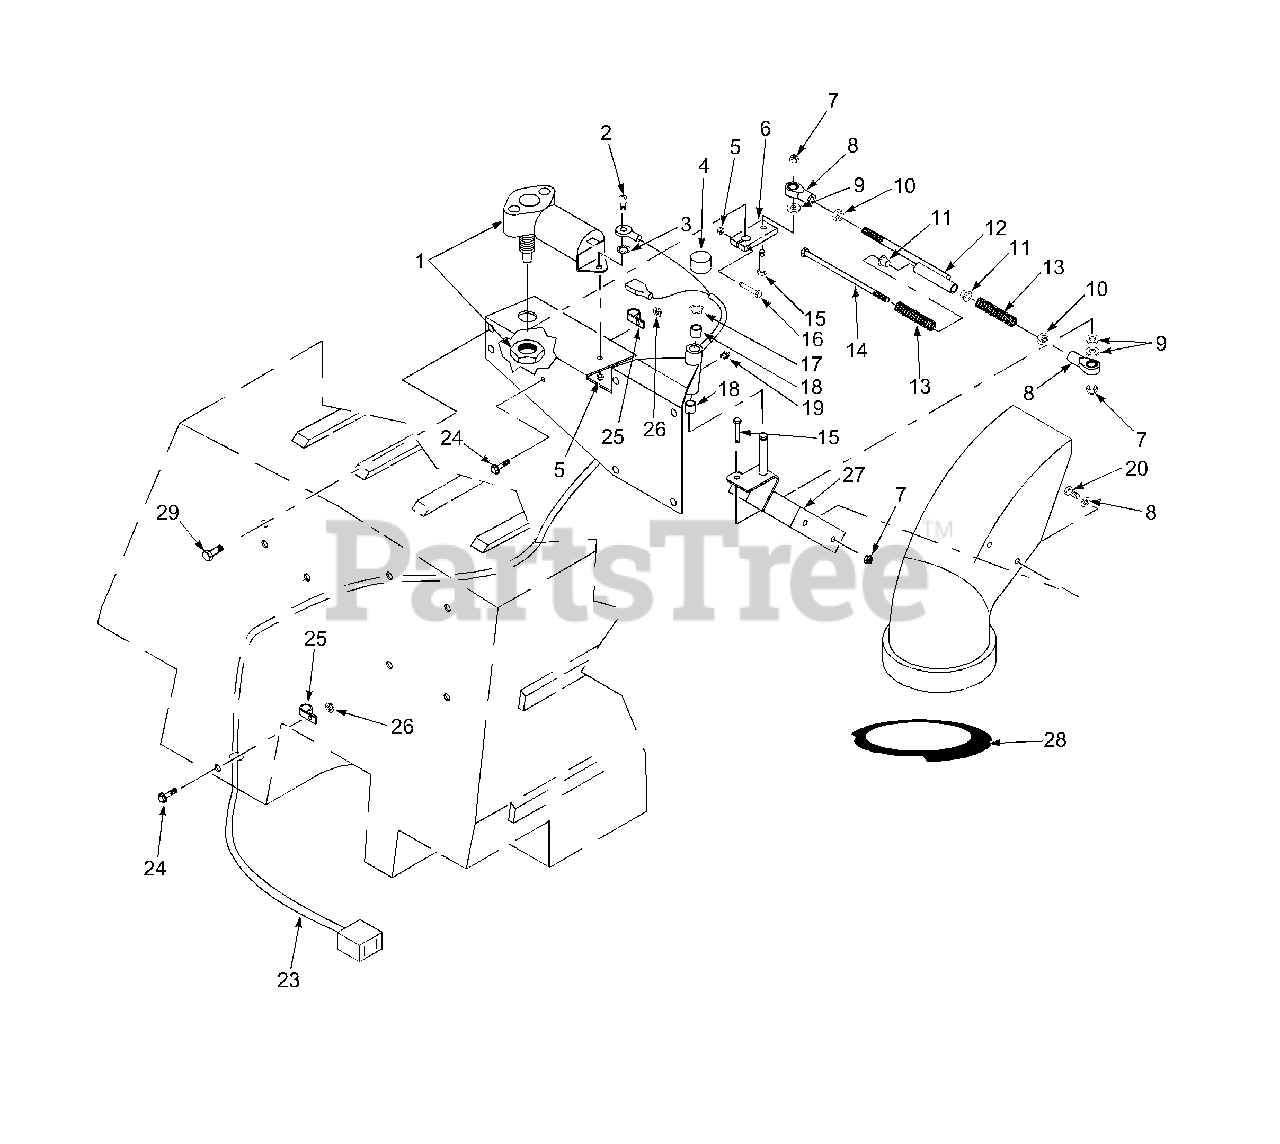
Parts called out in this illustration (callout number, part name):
1	Motor, Actuator
2	Capscrew, Socket Head, #10-32 x 1/2"
3	Washer, External
4	Cap, Plastic
5	Hex Locknut, Elastic Stop, #10-32
6	Lever, Actuator
7	Hex Locknut, Elastic Stop, 5/16-18
8	Rod End, 5/16-24 R.H. Thread
9	Flatwasher, 5/16 (.375 x .875 x .083)
10	Hex Nut, 5/16-18
11	Bushing, Nylon
12	Connecting Rod
13	Spring, Connecting Rod
14	Bolt, Hex Head, 5/16-18 x 7.00"
15	Bolt, Hex Head, 5/16-18 x 1-1/4"
16	Capscrew, Socket Head, #10-32 x 1-1/2"
17	Retainer Ring
18	Bushing, Oilite, .502 ID
19	Grease Fitting
20	Bolt, Hex Head, 5/16-18 x 3/4"
23	Wire Harness, Hopper
24	Bolt, Carr. 1/4-20 x 3/4"
25	Clamp, Cable, 1/2"
26	Serr. Fl. Hex Nut, 1/4-20
27	Pivot, Elbow
28	Seal, Hopper Elbow
29	Body Bolt, 5/16-18 x .81"
